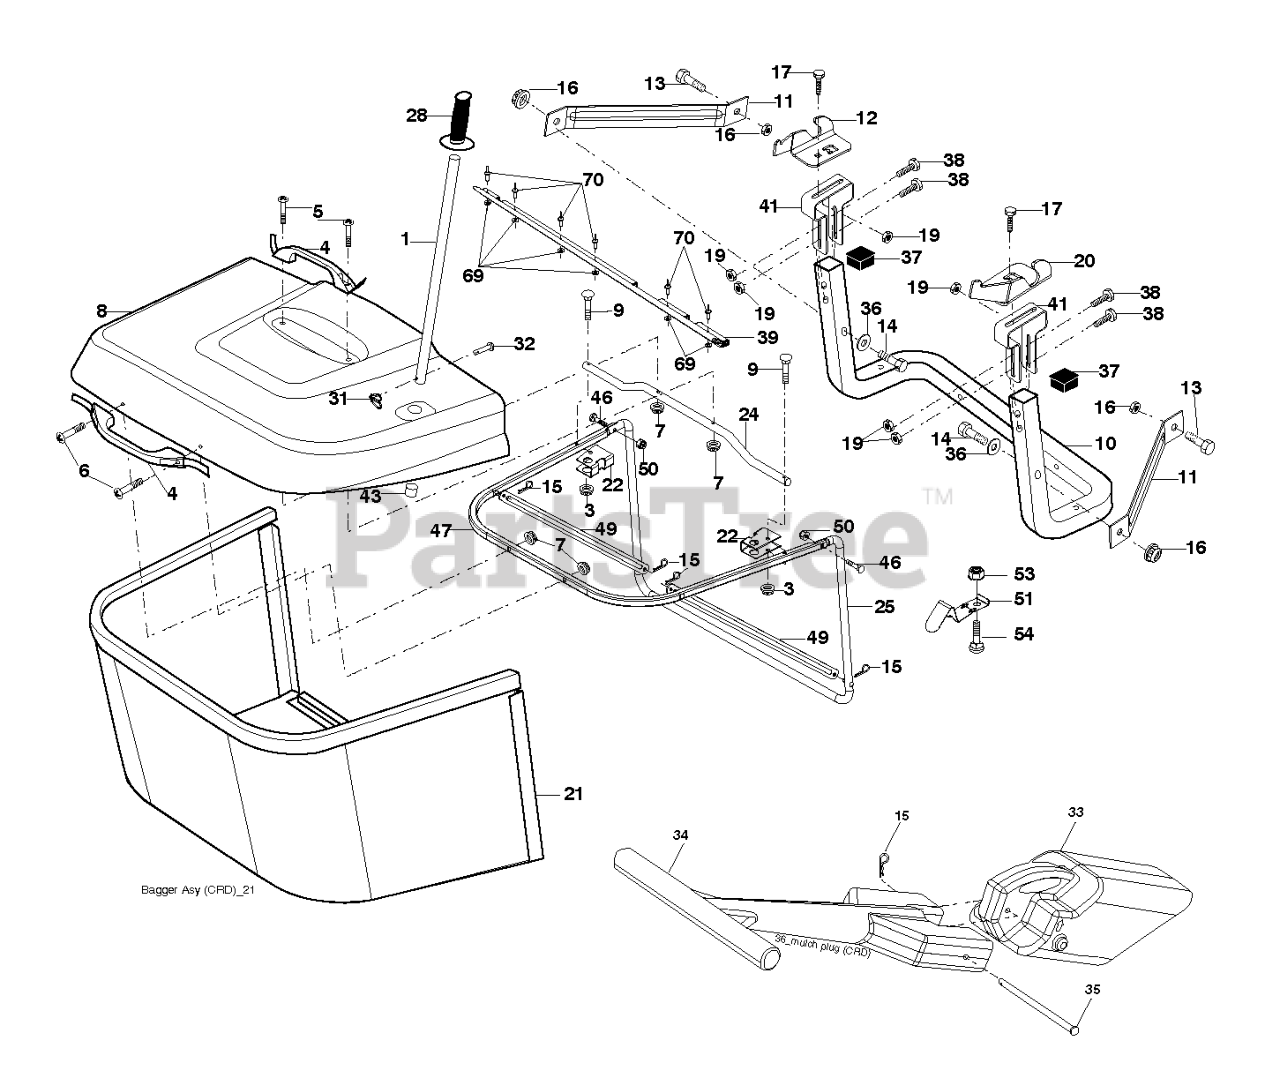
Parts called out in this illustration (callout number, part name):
1	TUBE.HANDLE.BAGGER.CRD/SRD.BLA
3	NUT T
4	HANDLE.BAGGER.W/LVRS.BLK.CRD
5	SCREW.PAN.HEAD
6	REPL BY 532 75 00-29
8	COVER.PNT.BGR.CRD.WSLOTS.MS668
10	TUBE
11	BRACKET.SUPPORT.UPPER.BAG.CRD
12	BRKT PIVOT
14	BOLT-HEX EAK
15	RETAINER-SPRNG RB
16	NUT LOCK FLG 3/8-16 UNC
17	RP BOLT 5/16-18 X3/4 ZN/YEL GR
19	NUT LOCK HEX FLANGE 5/16-18
20	BRKT.PIVOT.RH.CRD
21	BAGGER.ASM.CRD.2007
22	BRACKET.BAGGER.SD.ELECTRIC.CRD
24	TUBE.PIVOT.BAG.CRD.BLACK
25	PIPE
28	GRIP.HANDLE.BLACK
31	RETAINER CLIP
32	RIVET,DRILLED
33	MULCHING.PLUG.107.CRD.(2 2)
34	HANDLE.MULCHER.92.CRD (2 2)
36	WASHER
37	PLUG PLUG.SUPPORT.BAGGER.CRD
38	BOLT.5/16-18X2.5
39	SEAL.BAGGER.CRD
41	BRACKET.BAGGER.SD.ELECTRIC.CRD
43	PLUG, TUBING END
46	BOLT.CARRIAGE.5/16-18
47	PIPE
49	ROD
50	NUT.71038.31-18.HEX.NYLOCK
51	LATCH
53	NUT
54	BOLT
69	WASHER
70	RIVET RIVET POP
